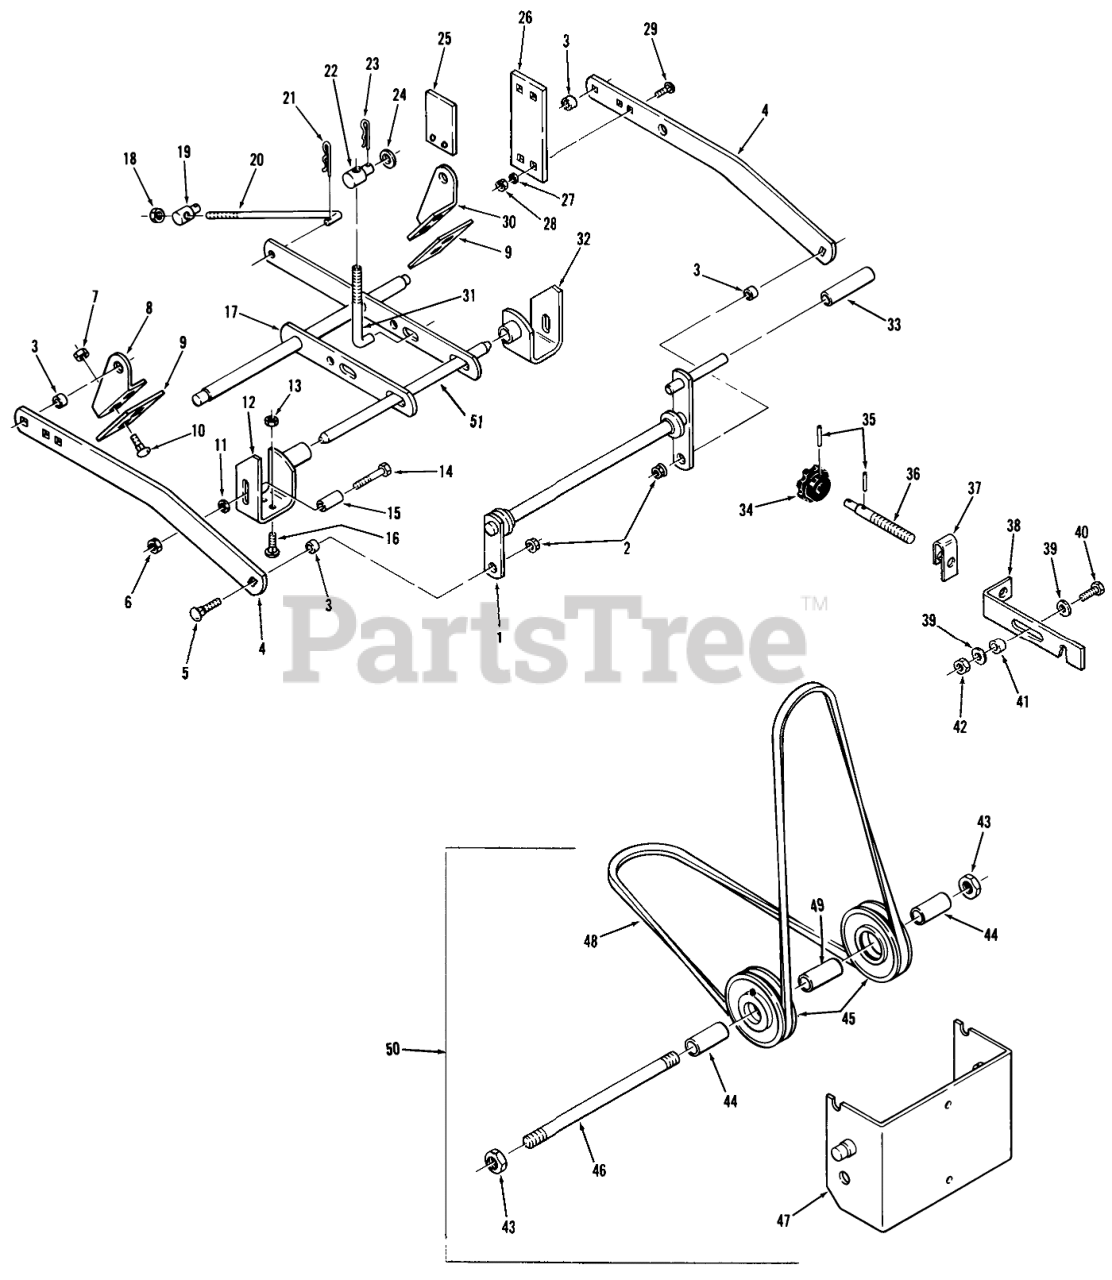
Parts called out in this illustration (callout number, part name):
1	Hitch Assy.
2	LOCKNUT-FLANGE
3	SPACER
4	Bar Draft
5	Bolt
6	Nut
7	Nut
8	Bracket-R.H.
9	PLATE
10	Bolt-Carriage
11	WASHER
12	Bracket-RH Front
13	Nut
14	7/16-14X13/4 HEX BLT
15	SPACER-BEARING
16	Bolt-Carriage
17	Leveler Ass-y.
18	NUT
19	TRUNNION-LIFT
20	ROD-LEVELER
21	Hairpin Cotter
22	ROD-TRUNNION LIFT
23	Hairpin
24	Washer
25	BUMPER
26	PLATE-BUMPER R
27	Collar
28	Nut
29	Bolt-Carriage
30	Bracket-L.H.
31	LIFT ROD
32	LH FT DECK BRKT A R
33	GRIP
34	KNOB-ADJUSTMENT
35	PIN-ROLL
36	HITCH ADJ SCREW
37	Detent Spring
38	Hitch Adjustment Link
39	Washer
40	Bolt
41	SPACER
42	Nut
43	Nut
44	SPACER FRONT PULL R
45	Pulley-V
46	SHAFT FRONT PULLEY
47	Shield Assy.
48	V BELT
49	SPACER-FRONT PULLEY
50	S.A. Front Idler-Complete
51	SHAFT-FRONT R
